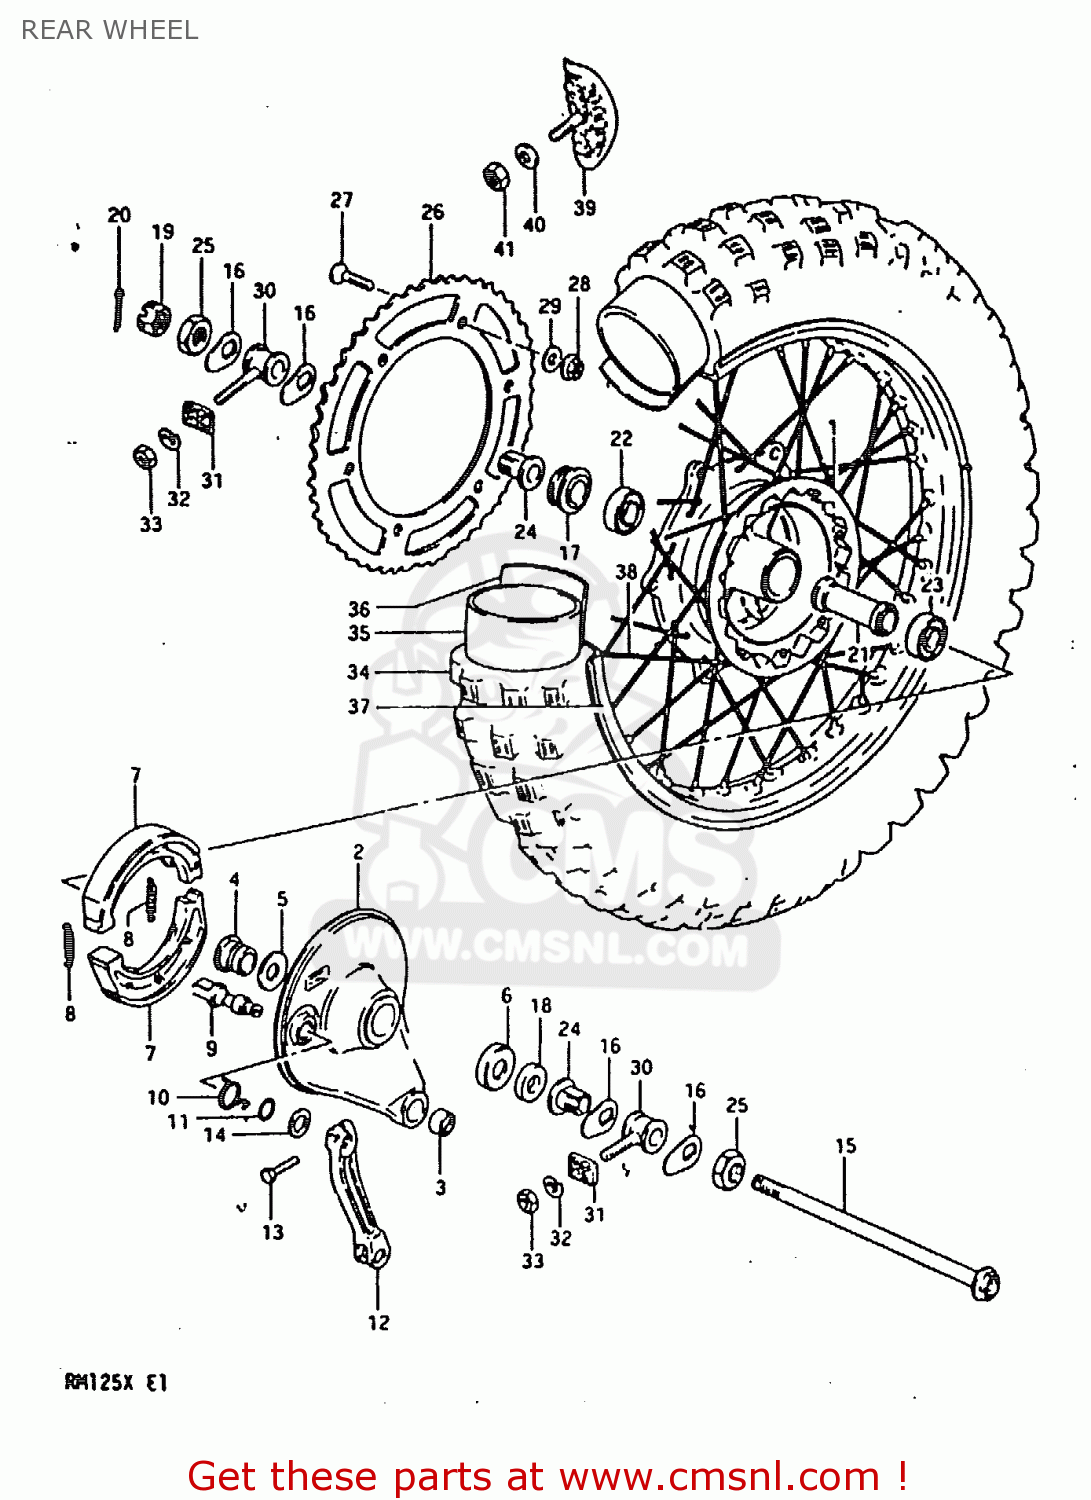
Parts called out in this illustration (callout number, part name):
1	DRUM,REAR HUB
2	PANEL SET,REAR HUB
3	SPHERICAL BRNG,TORQUE LINK
4	SPACER,RR BRAKE ANCHOR PANEL
5	SEAL,OIL(20X27X5)
6	CVR,RR BRAKE AHR PNL DUST SEAL
7	SHOE,BRAKE (MCA)
8	SPRING(L:34)
9	CAM,FRONT BRAKE
10	SPRING
11	O RING(D:2.5,ID:11.4)
12	LEVER,RR BRAKE CAM
13	BOLT
14	WASHER(12.5X20X1)
15	AXLE,REAR
16	WASHER,CHAIN ADJUST GUIDE
17	SPACER,RR AXLE,L
18	SPACER,REAR AXLE,RIGHT
19	NUT
20	COTTER PIN
21	SPACER,REAR HUB BEARING
22	BEARING
23	BEARING
24	SPACER,CHAIN ADJUSTER
25	NUT
26	SPROCKET,RR(NT:51 AL)
27	SCREW(8X33.5)
28	NUT
29	WASHER
30	ADJUSTER,CHAIN
31	PLATE,CHAIN ADJUSTER GUIDE,R
32	LOCK WASHER
33	NUT
34	TIRE
35	TUBE ASSEMBLY,WHEEL,INNER
36	PROTECTOR,INNER TUBE
37	RIM,REAR WHEEL
38	SPOKE SET,REAR WHEEL
39	STOPPER,BEAD
40	WASHER
41	NUT
